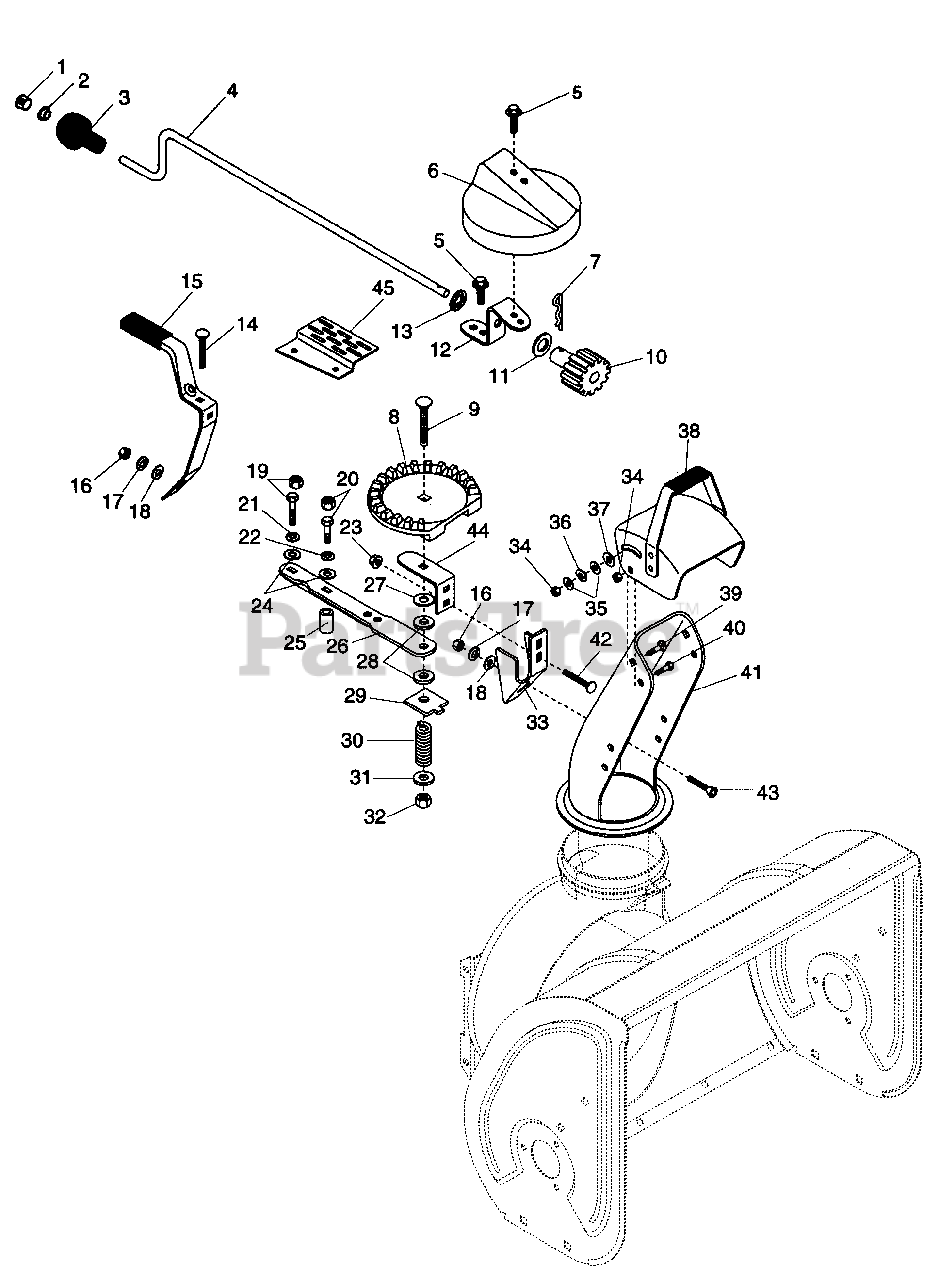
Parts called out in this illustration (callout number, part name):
1	HOLE PLUG
2	RG-RTNG-EXT .375X.010
3	KNOB
4	CHUTE CRANK
5	SCR-TAP .250-20X.50 HXSLHDPL
6	GEAR COVER
7	PIN-HAIR INT .08X.38X1.42 YWZC
8	CHUTE GEAR
9	BLT-RDHDSQNK .38-16X2.25 SHTPL
10	PINION-CHUTE
11	WSHR-FL-STL .630X1.005X.062 PL
12	BRACKET-GEAR
13	PUSHNUT .625
14	BLT-RDHDSQNK .38-16X2.00 SHTYW
15	CHUTE HANDLE W/PLASTISOL
16	NUT-HEX .250-20 PL
17	WSHR-LK .250X.077 HVY PL
18	WSHR-FL-STL .380X.875X.179 PL
19	BLT-HEX .31-18X.63 PL GR 2
19	BLT-HEX .31-18X1.25 PL GR5
19	NUT-HEX .312-18
19	NUT-LK .312-18 GR A PL
20	BLT-HEX .25-20X1.50 PL GR5
20	BLT-HEX .31-18X1.25 PL GR5
20	NUT-HEX .312-18
20	NUT-LK .312-18 GR A PL
21	WSHR-LK .312X.097 PL HVY
22	WSHR-LK .250X.077 HVY PL
22	WSHR-LK .312X.097 PL HVY
23	NUT-LK-FLG .250-20 PL
24	WSHR-FL-STL .328X.875X.062 PL
25	SPACER .280X.625X.760
25	SPACER .280X.625X.640
25	SPACER .322X.626X.50
26	STRAP
26	STRAP-CHUTE CONTROL
26	STRAP-DISCHARGE CHUTE SUPPORT
27	WSHR-FL-STL .380X1.50X.062 PL
28	FRICTION WASHER
29	FRICTION PLATE
30	SG-COMP .187X.56X1.62
31	WSHR-FL-STL.406X.812X.065PL
32	NUT-LK-CTR .375-16 GR A PL
33	STRAP, CHUTE
34	NUT-LK .312-18 GR A PL
35	WSHR-FL-STL .323X.625X.062 PL
36	WAVE WASHER .390X.655X.110
37	WSHR-PLASTIC .390X.875X.062
38	DEFLECTOR W/DECAL
39	BLT-RDHDSQNK .31-18X.75 SHT PL
40	BLT-HEX .31-18X.50 PL GR2
41	DISCHARGE CHUTE
41	CHUTE-DISCHARGE
42	BLT-RDHDSQNK .25-20X.62 PL
43	SCR-SKH .25-20X.75 FLTCNTRSK
44	GEAR STRAP
45	MUFFLER SHIELD
